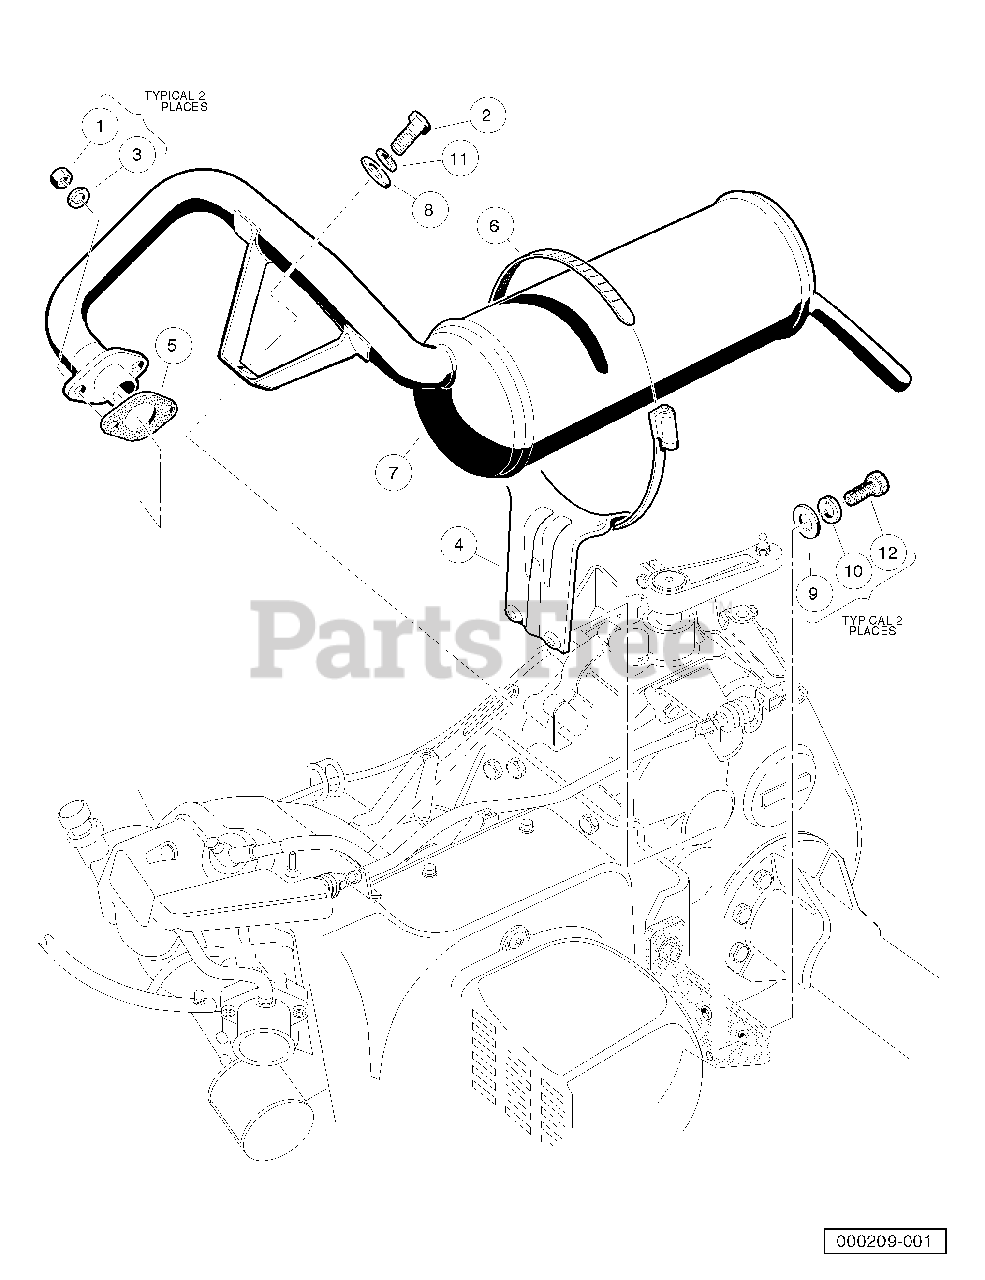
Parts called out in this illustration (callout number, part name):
1	Nut, M8-1.25 Hex
2	Screw, M8-125 X 22 Hex-Head
3	Lockwasher, 8mm Split
4	Bracket, Muffler Mounting
5	Gasket, Exhaust
6	Clamp, 5" Muffler Hose
7	Exhaust System, FE350
8	Washer, 5/16 Type A Flat
9	Washer, 1/4 Type A Narrow Flat
10	Lockwasher, 1/4 Helical Split
11	Lockwasher, 5/16 Split
12	Screw, 1/4-20 X 0.75 Hex-Head Cap
